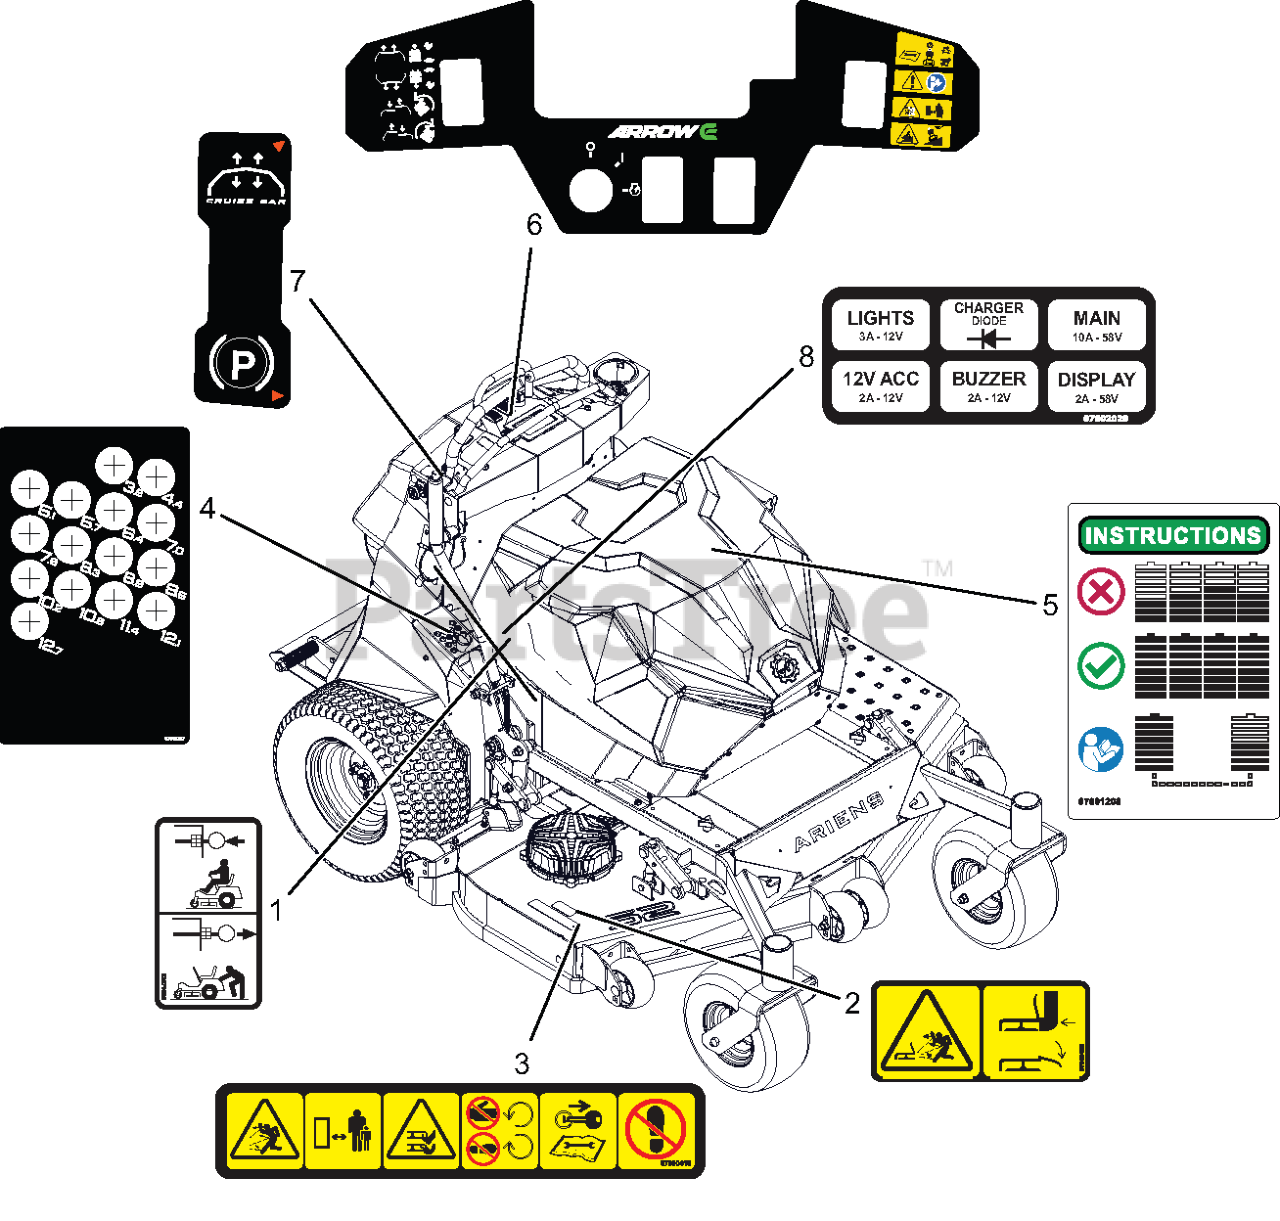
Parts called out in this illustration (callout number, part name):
1	DECAL, TRANSMISSION DISCONNECT
2	DECAL, SAFETY - DECK GUARDING
3	DECAL, DECK SAFETY
4	DECAL, ARROW E HEIGHT ADJUST
5	DECAL, BATTERY BALANCE
6	DECAL, ARROW E DASH
7	DECAL, ARROW E DASH CRUISE BAR
8	DECAL, FUSE LAYOUT
